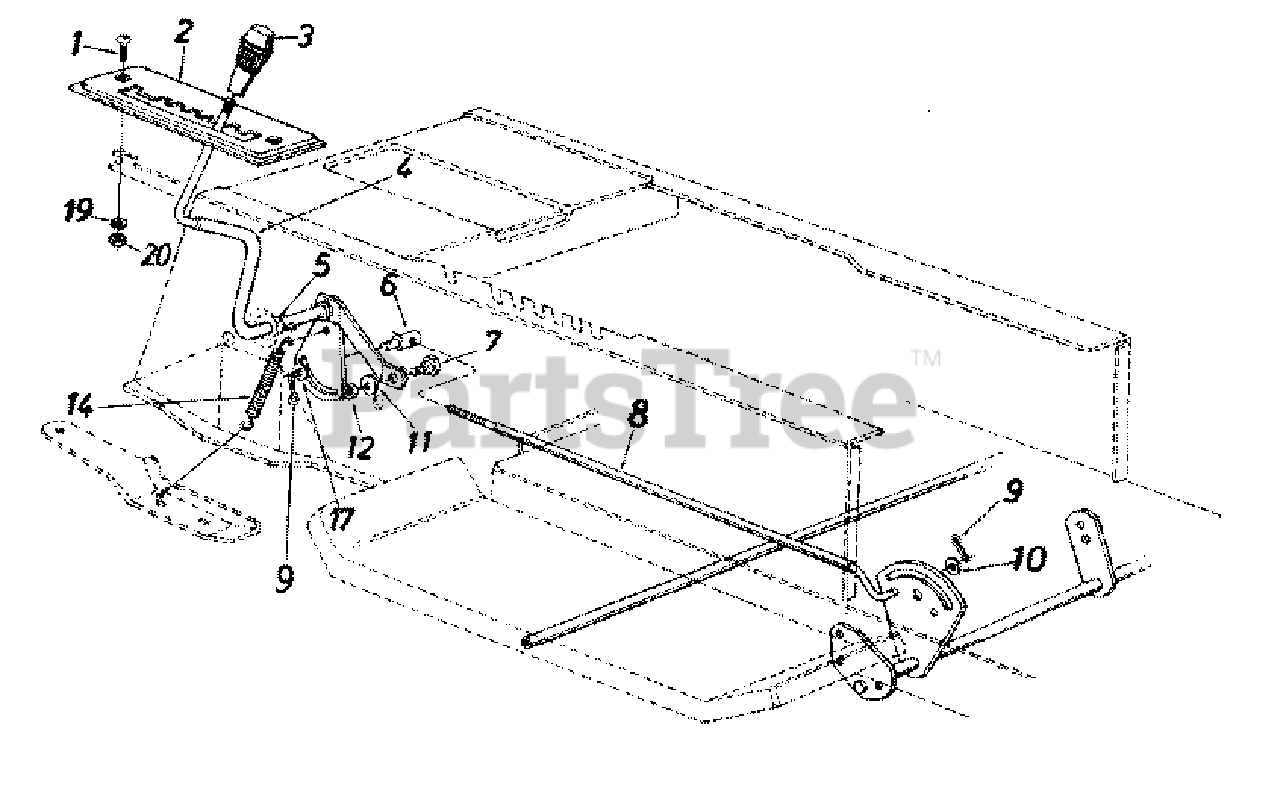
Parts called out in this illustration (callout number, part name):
1	Truss Mach. Scr. 1/4-20 x .75" Lg.
2	8-Speed Selector Plate
4	Speed Selector Lever Ass'y.
5	Flat Washer .53" I.D. x .93"
6	Ferrule 3/8-24 x .37" Dia.
7	Shoulder Bolt
8	Speed Control Link
9	Cotter Pin 3/32" Dia. x 1.0"
10	Fl-Wash. .469" I.D. x .88"
11	L-Wash. 5/16" I.D.
12	Hex Nut 5/16-18 Thd. (Gr. 5)
14	Spring .38" O.D. x 3.18" Lg.
17	Fl-Wash. .385" I.D. x 7/8"
19	L-Wash. 1/4" I.D.
20	Hex Nut 1/4-20 Thd. (Gr.5)
